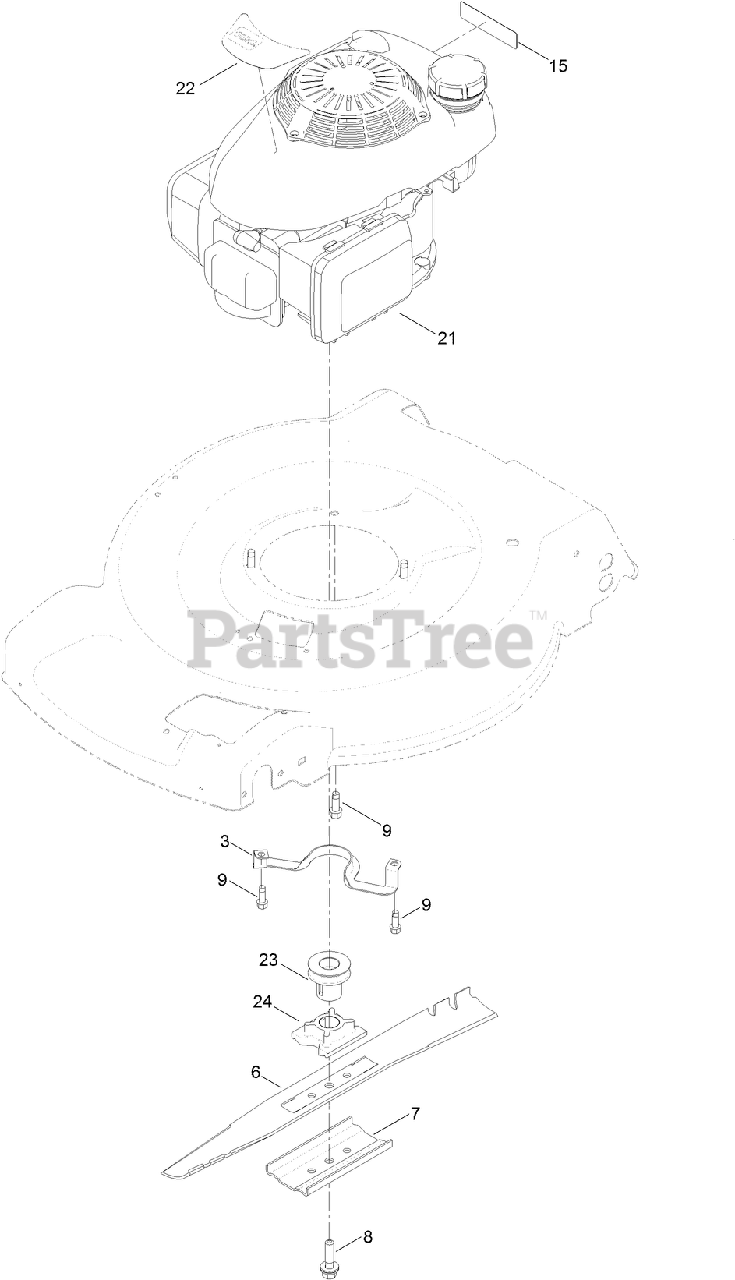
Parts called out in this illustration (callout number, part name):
3	GUIDE-BELT
6	BLADE-22 INCH
7	SUPPORT-BLADE
8	BOLT-BLADE
9	SCREW-TAPTITE
15	DECAL-ARRESTER, SPARK
22	DECAL-SHROUD, HONDA
23	PULLEY
24	RETAINER-BLADE
